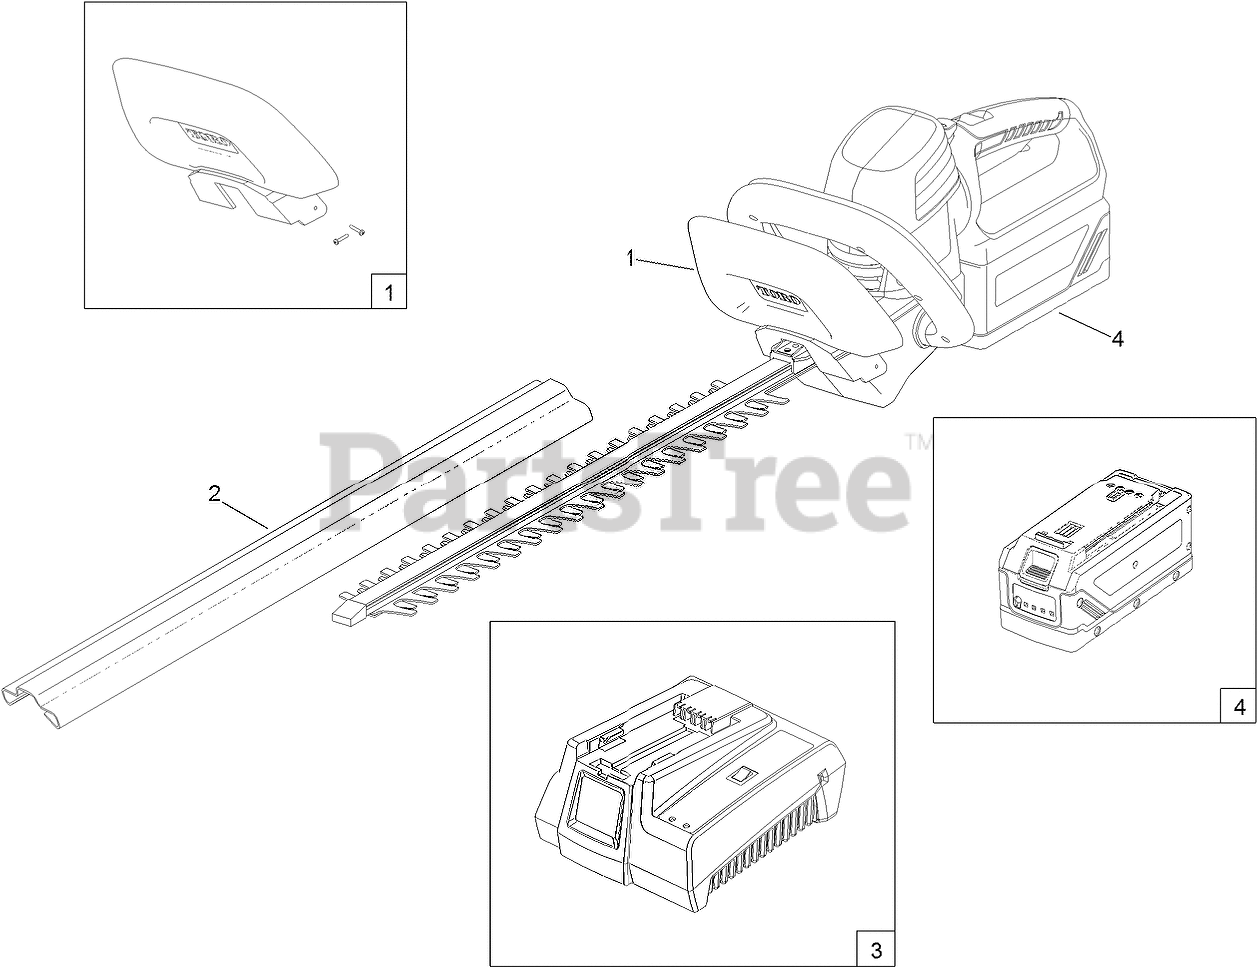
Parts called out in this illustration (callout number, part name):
1	GUARD ASM
2	SHEATH-BLADE
3	CHARGER-REPLACEMENT, 48V
4	BATTERY-REPLACEMENT, 48V
